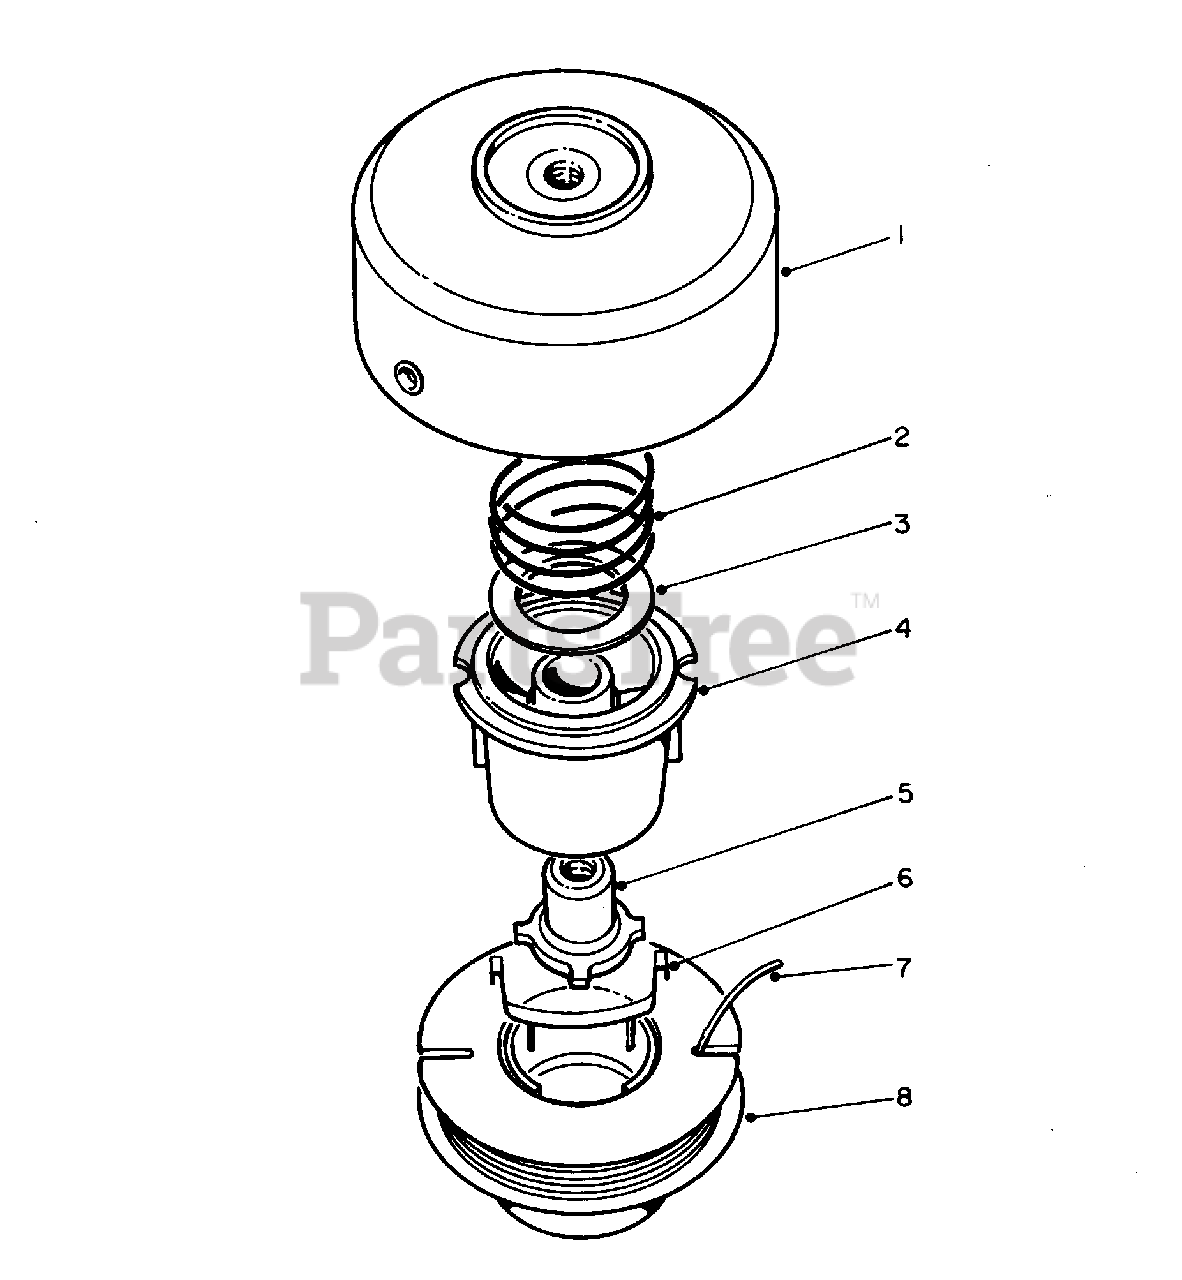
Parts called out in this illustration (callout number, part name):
1	Drum w/Eyelet
4	Spool Core
5	Driver L.H.
6	Saddle C
7	1 Lb. Filament Line Pack (.0
8	Prewound Spool
